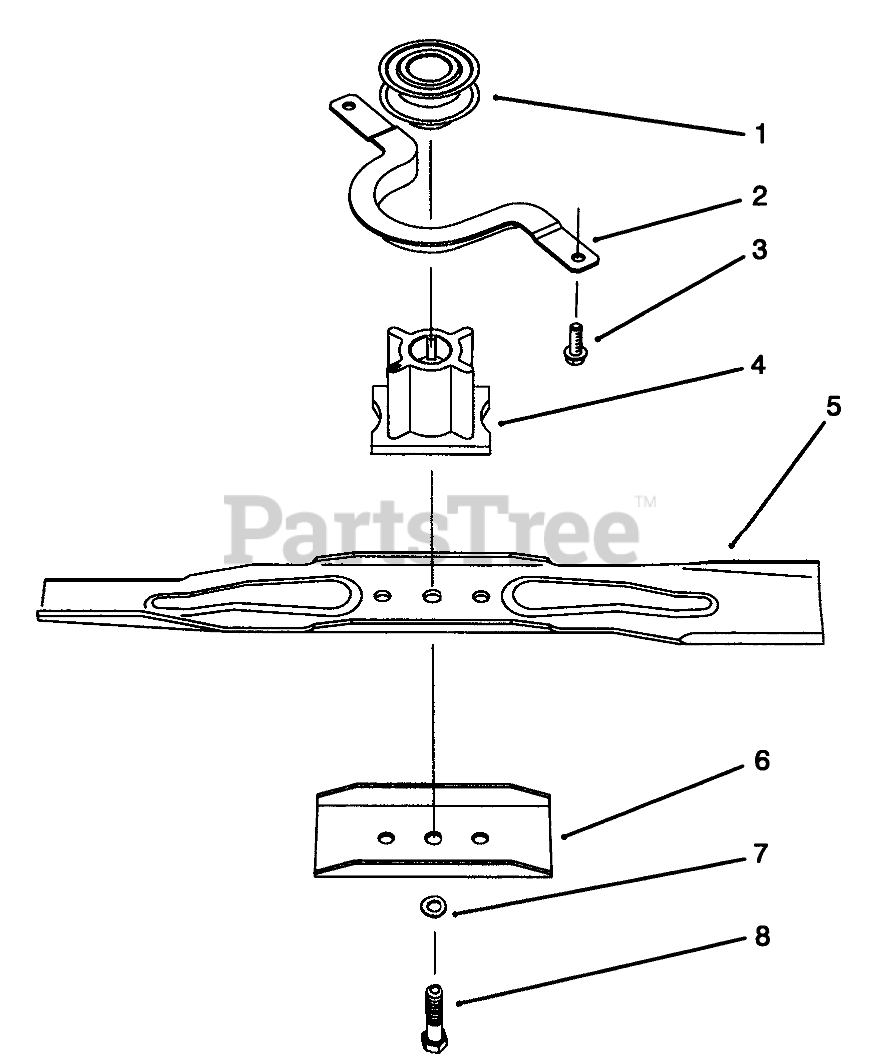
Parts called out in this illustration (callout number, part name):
1	PULLEY-DRIVE, ZONE START
2	Guide-Belt
3	SCREW-HWH
4	BLADE RETAINER - 25 MM
5	Blade
6	Stiffener
7	WASHER-LOCK
8	BOLT-BLADE
